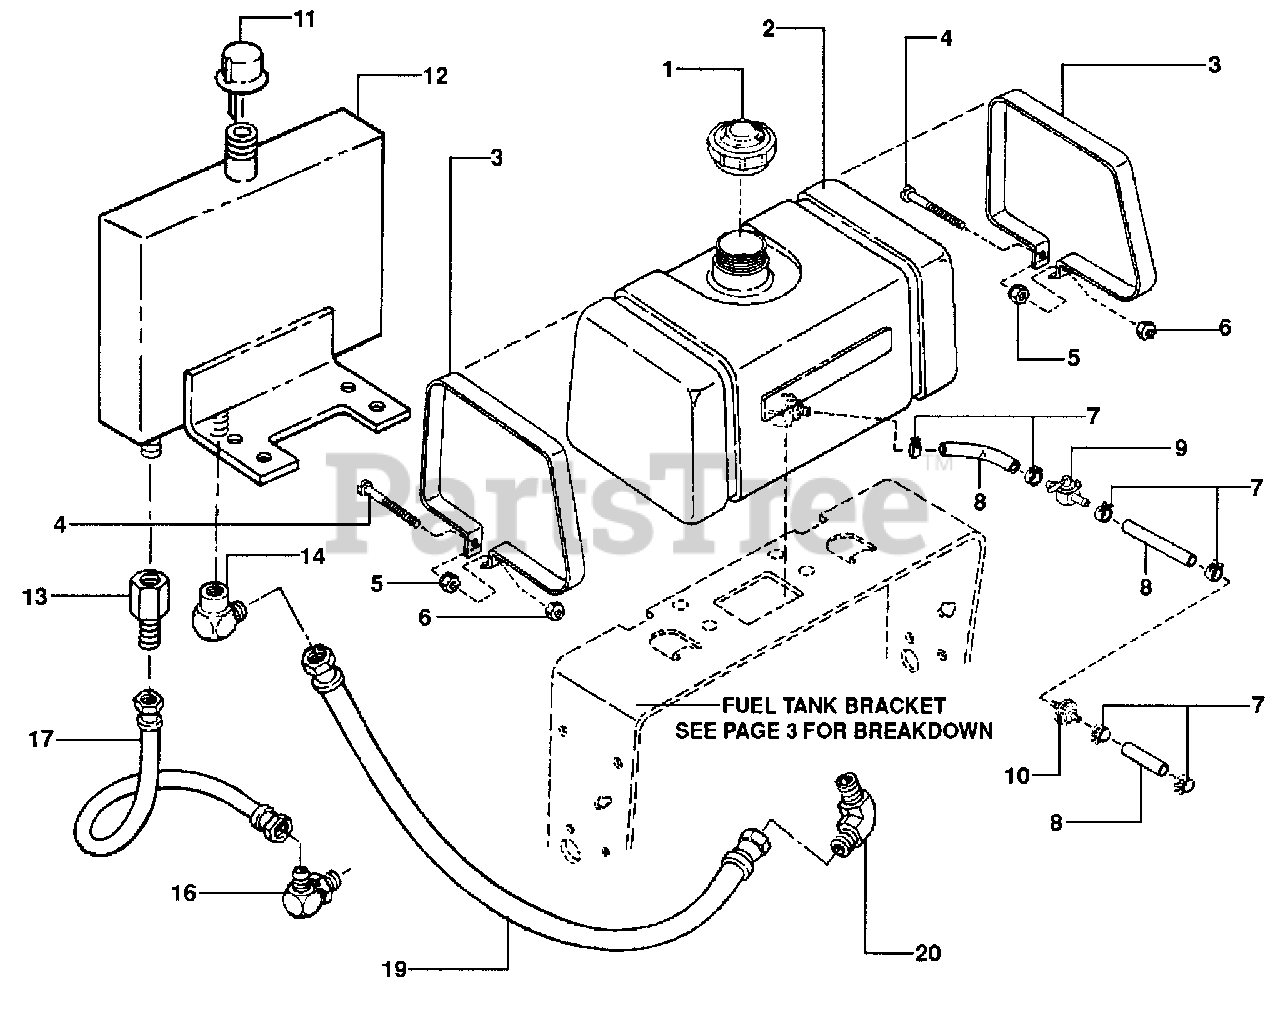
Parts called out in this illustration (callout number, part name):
1	TANK, Fuel
2	CAP, Fuel
3	STRAP, Fuel Tank
4	SCREW, #10-24 X 2" Machine Head
5	NUT, #10-24 Keps
6	NUT, #10-24 Nyloc
7	CLAMP, Fuel Hose
8	HOSE, Fuel 7"
9	VALVE, Fuel Shut-Off
10	FILTER, Fuel In-Line
11	CAP, Hydraulic
12	TANK, Reservoir
13	FITTING, Straight
14	FITTING, 90°.
16	FITTING, 90°.
17	HOSE, 9" Hydraulic
19	HOSE, 12" Hydraulic
20	FITTING, 90°.
